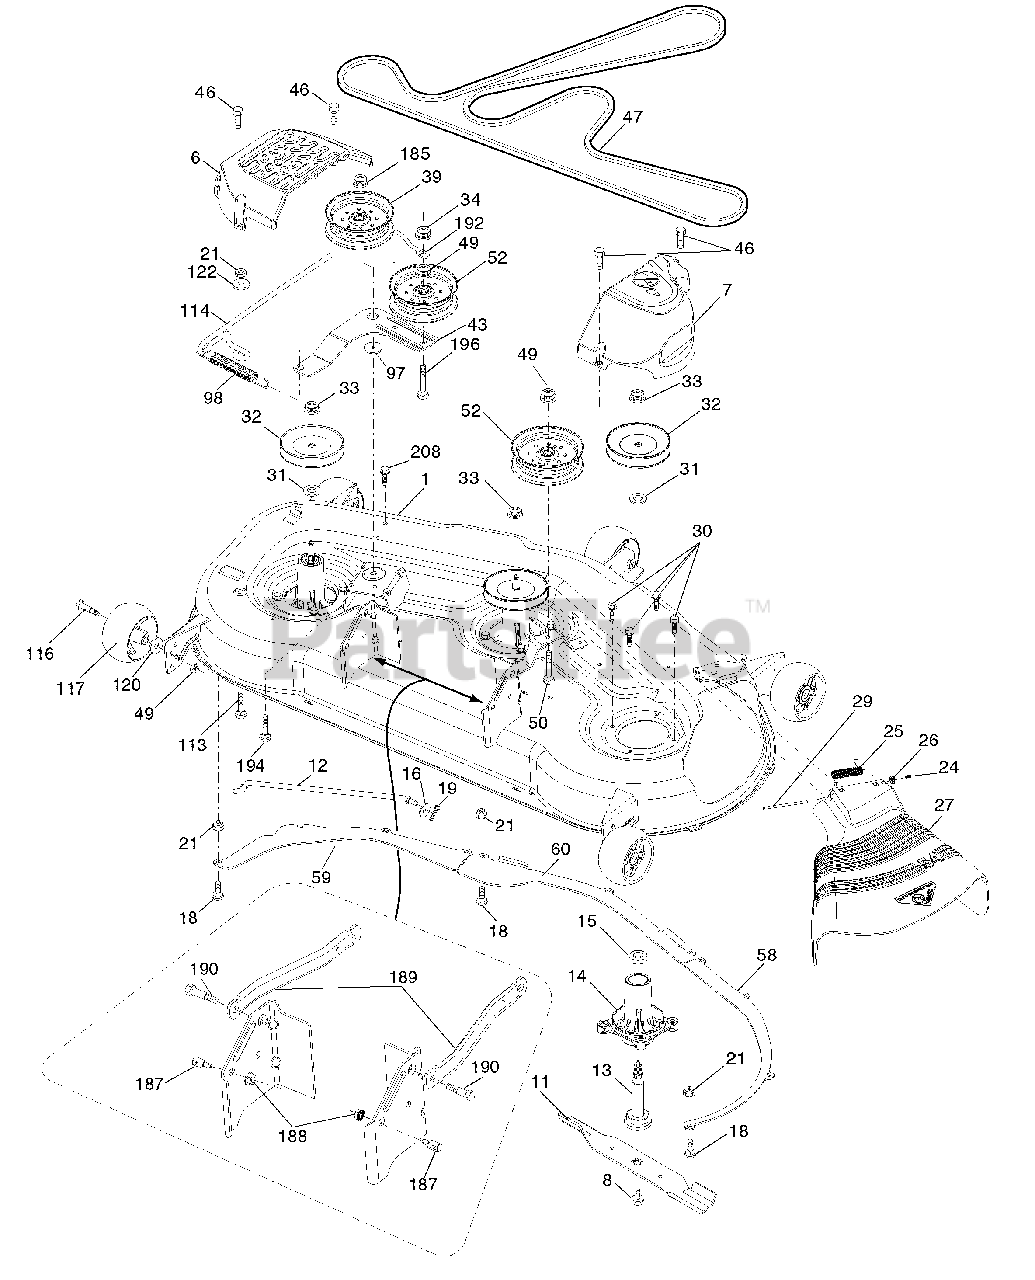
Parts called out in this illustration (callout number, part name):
1	Deck Weldment Mower
6	Cover Mandrel LH
7	Cover Mandrel RH
8	Bolt 7/16 Asm. Blade
11	Blade Bagging
11	Blade Discharge
11	Blade Mulching
12	Rod Anti Sway
13	Shaft Asm. w/Lower Bearing
14	Housing, Mandrel
15	Bearing, Ball, Mandrel
16	Washer 3/8
18	Bolt Carriage 5/16-18 x 5/8
19	Pin Cotter 5/16 Bowtie
21	Nut, Crownlock 5/16-18 unc
24	Cap Sleeve
25	Spring, Torsion
27	Deflector Shield
29	Rod, Hinge
30	Screw, Thdroll Washer Head
31	Washer, Spacer Mower Vented
32	Pulley, Mandrel
33	Nut, Flg. Top Lock
34	Nut Crownlock 3/8-16 unc
39	Pulley, Idler, 4.50
43	Arm, Idler
46	Screw, Thdroll. 1/4-20 x 5/8
47	Belt Deck Drive
49	Nut, Lock Flg. 3/8-16 unc
50	Bolt Rdhd Sqnk 3/8-16 unc x 2
52	Pulley Idler
58	Baffle Right
59	Baffle Left
60	Baffle Center
97	Washer Hardened
98	Spring Drive
113	Bolt Rdhd Sqnk 5/16-18 x 3/4
114	Rod Tension Relief
116	Bolt, Shoulder
117	Gauge Wheel
120	Washer 13/32 x 1-1/4 x 12 Ga.
122	Bushing Tension Relief
185	Nut Lock Flange 7/16-14 Gr. 5
187	Stud Fastener w/"D" Anti-Rotation
188	Nut Lock Hex Flange
189	Arm Susp. Mower Rear
190	Bolt Shoulder
192	Keeper Belt Idler
194	Bolt Carr Sqnk 7/16-24 x 2
196	Bolt Rdhd 3/8-16 x 2-1/2 Gr. 5
208	Screw THDROL 3/8-16 x 1/2
208	Mandrel Asm. Service Mandrel Assembly
208	Replacement Mower, Complete
